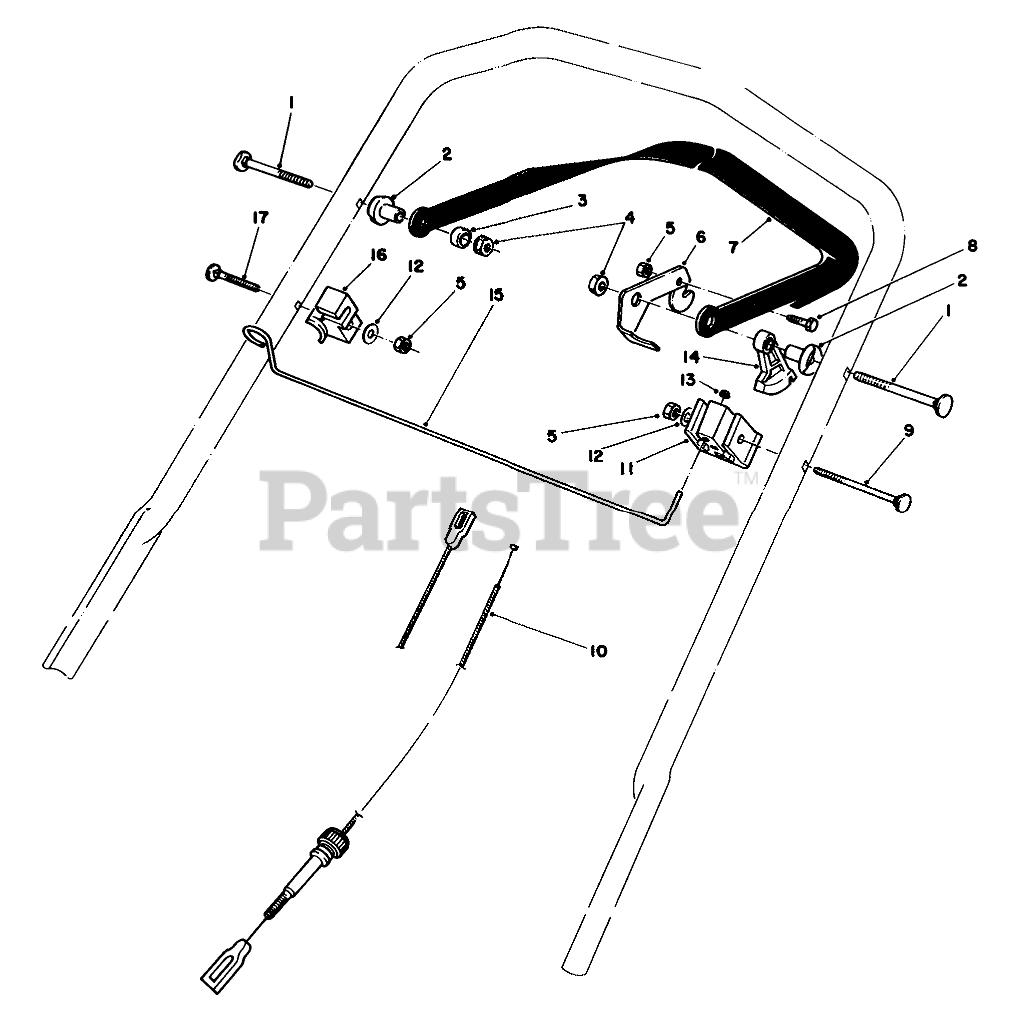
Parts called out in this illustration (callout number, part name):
1	5/16-18 X 2 HNDLE SCREW
2	SPACER-SUPPORT
3	SPACER-NYLON
4	NUT-LOCK, NI
5	NUT-LOCK, NI
6	Lever-Control
7	Bar-Control
8	SCREW-HH
9	SCREW-HANDLE
10	CABLE-TRACTION
11	SUPPORT-CABLE
12	WASHER-FLAT
13	NUT-SPEED
14	LEVER-TRACTION
15	ROPE ROD PLATED
16	ROD CATCH
17	SCREW-HANDLE
